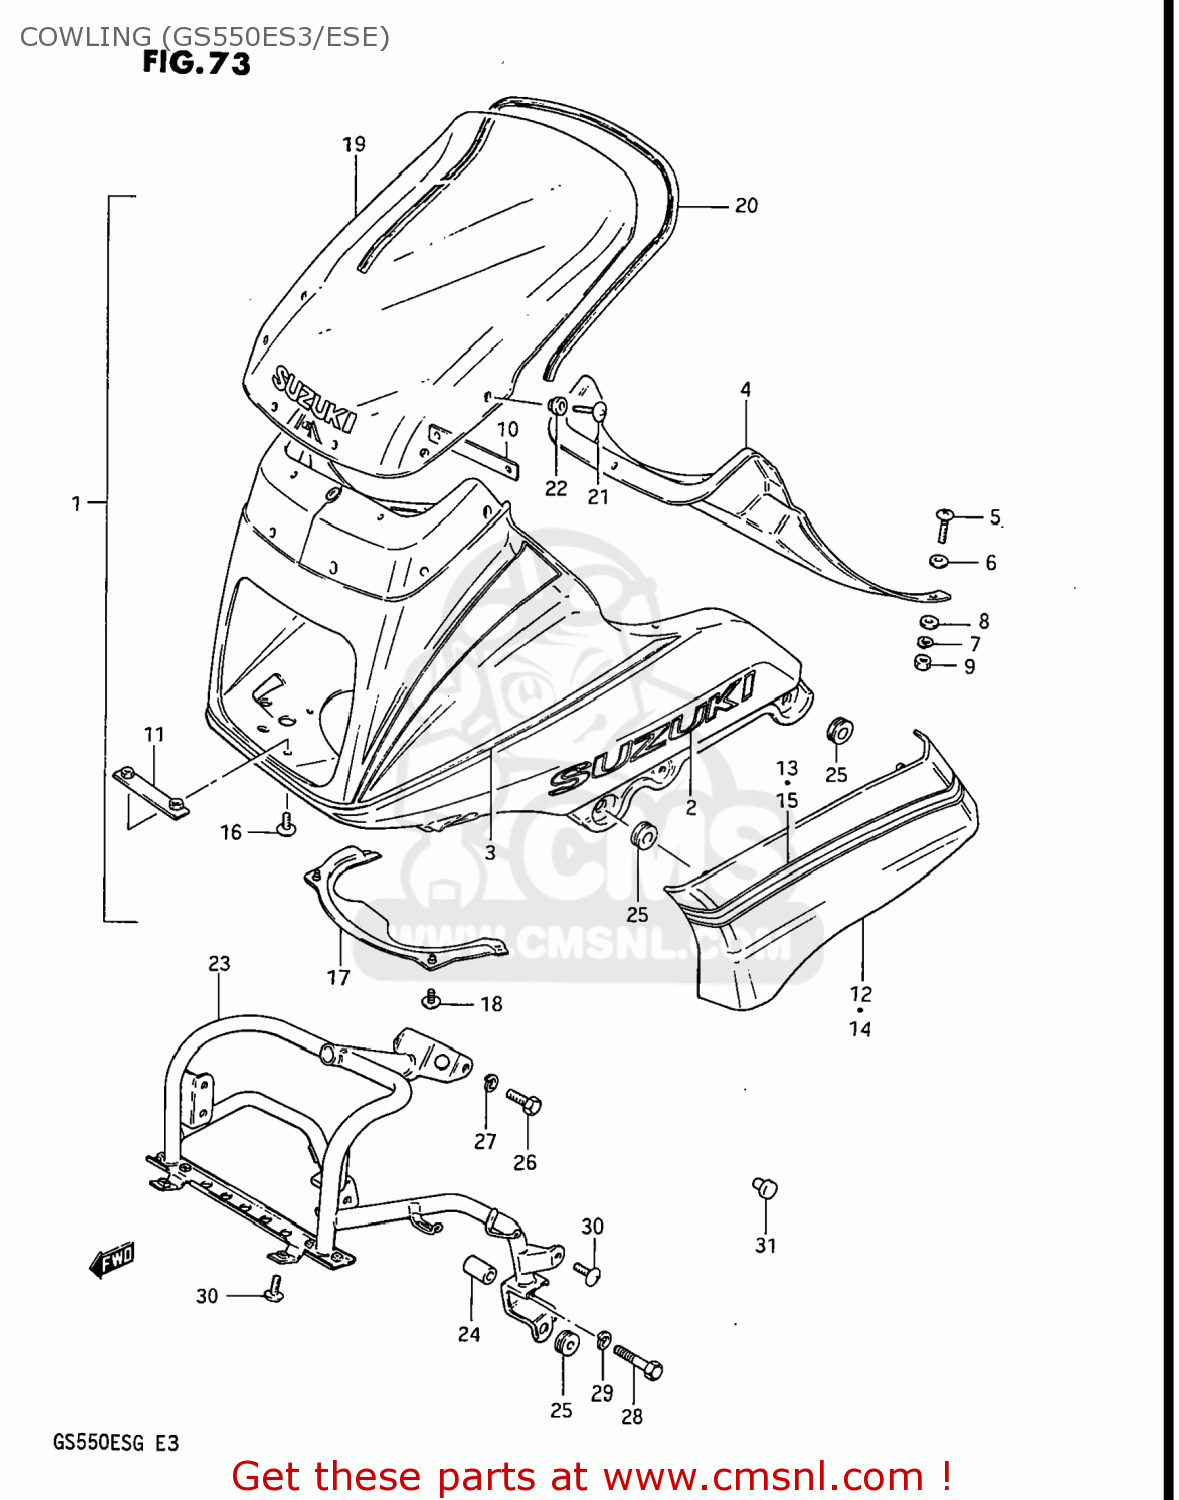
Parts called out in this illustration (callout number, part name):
1	COWLING ASSEMBLY
2	EMBLEM
3	TAPE SET,COWLING
4	PANEL,COWLING,UPPER
5	SCREW
6	WASHER,5MM
7	WASHER,LOCK
8	WASHER,5MM
9	NUT ,5MM
10	BRACKET,COWLING,UPPER
11	BRACKET,COWLING,LOWER
12	COVER,COWLING,RIGHT
13	TAPE SET,COWLING
14	COVER,COWLING,LEFT
15	TAPE SET,COWLING
16	SCREW
17	COVER,COWLING,LOWER
18	SCREW
19	WINDOW,COWLING
20	MOLDING,LOWER
21	SCREW
22	CUSHION
23	BRACE,COWLING
24	SPACER (8.2X12.5X23.5)
25	CUSHION
26	BOLT
27	LOCK WASHER
28	BOLT
29	LOCK WASHER
30	SCREW 6X12
31	PLUG
